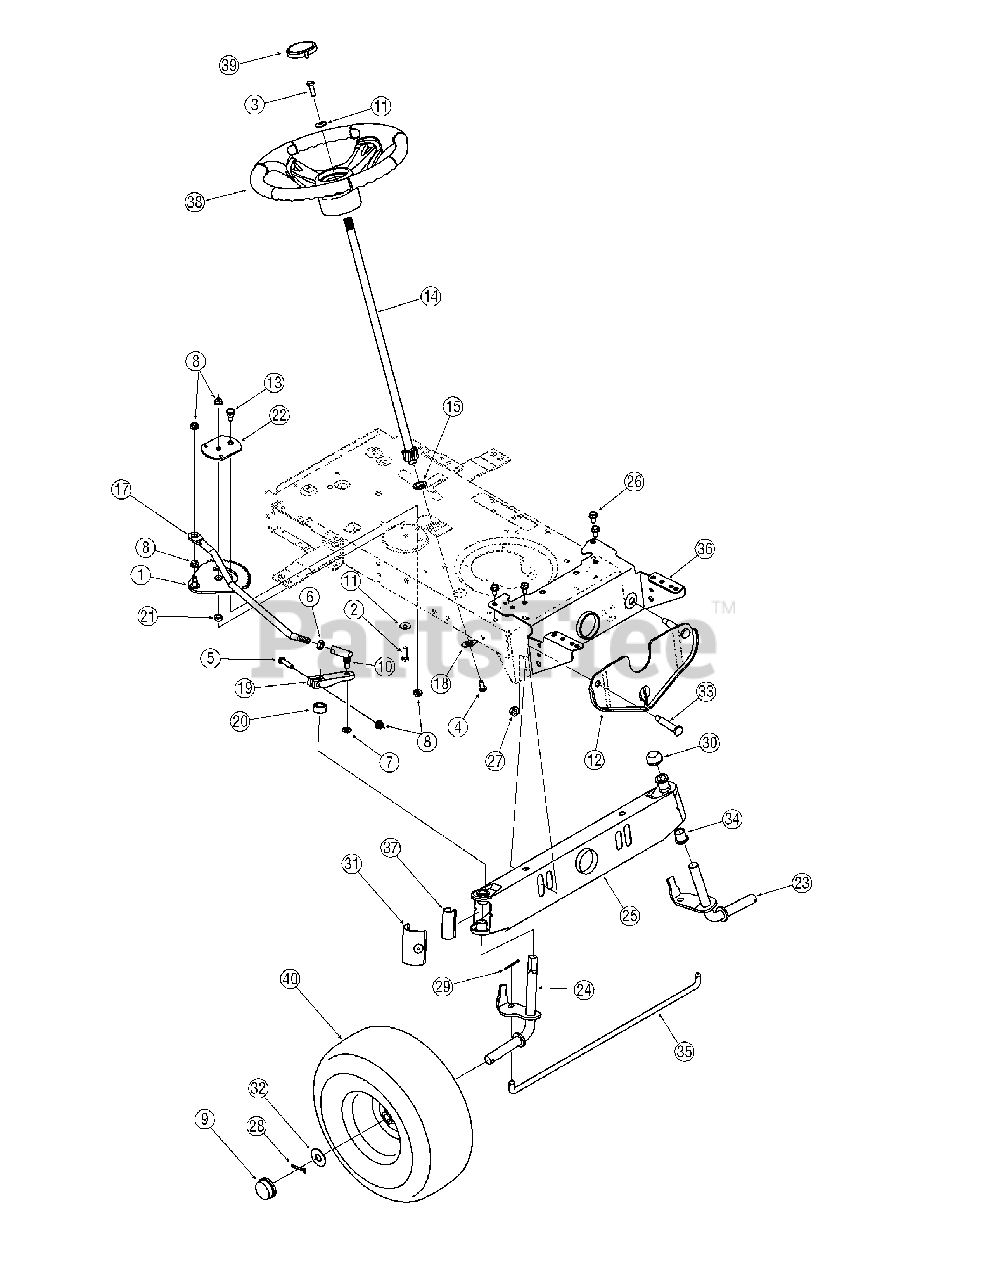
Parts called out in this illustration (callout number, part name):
1	Gear Assembly, Steering
2	Screw, 5/16-18, 1.00, Gr5
3	Screw, 5/16-18, 1.00, Gr5, Lock
4	Screw, Mach, 5/16-18, 0.750
5	Screw, 5/16-18, 1.75, Gr5
6	Nut, Jam, 7/16-20, Gr2
7	Nut, Jam Lock, 3/8-24, Gr2
8	Nut, Flange Lock, 5/16-18, Grf, Nylon
9	Hub Cap
10	Ball Joint, 7/16-20, Lock
11	Washer, Bell, .340 x .872 x .060
13	Screw, Shoulder, .435 x .3485, 5/16-18
14	Steering Shaft, 5/8 Spline x 21.86
15	Bearing, Flange, Hex 5/8
16	Plastic Bushing .380 ID
17	Drag Link, Steering
18	Cap, 1.25 x .16
19	Steering, Block
20	Spacer, .710 ID x .125 OD x .56
21	Spacer, .322 ID x .625 OD x .21
22	Stabilizer Plate, Gear Segment
23	Axle Assembly, LH
24	Axle Assembly, RH
26	Screw, 5/16-12, 0.750
27	Nut, Flange Lock, 3/8-16, GrF, Nylon
28	Pin, Cotter, 5/32, 1.25
29	Pin, Cotter, 1/8 x 1.25
30	Push Cap, 3/4
31	End Cap, Pivot Bar (w/ Fitting)
32	Washer, Flat, .78 x 1.59 x .060
33	Screw, Shoulder, .500 x 2.380, 3/8-16
34	Bearing, Flange, .760 x .941 x 1.0
35	Tie Rod
37	Axle End Cap, Standard
38	Steering Wheel, Standard Grip
38	Steering Wheel, Soft Grip
39	Cap, Steering Wheel (no logo)
39	Cap, Steering Wheel (sprig logo)
39	Cap, Steering Wheel (tine logo)
